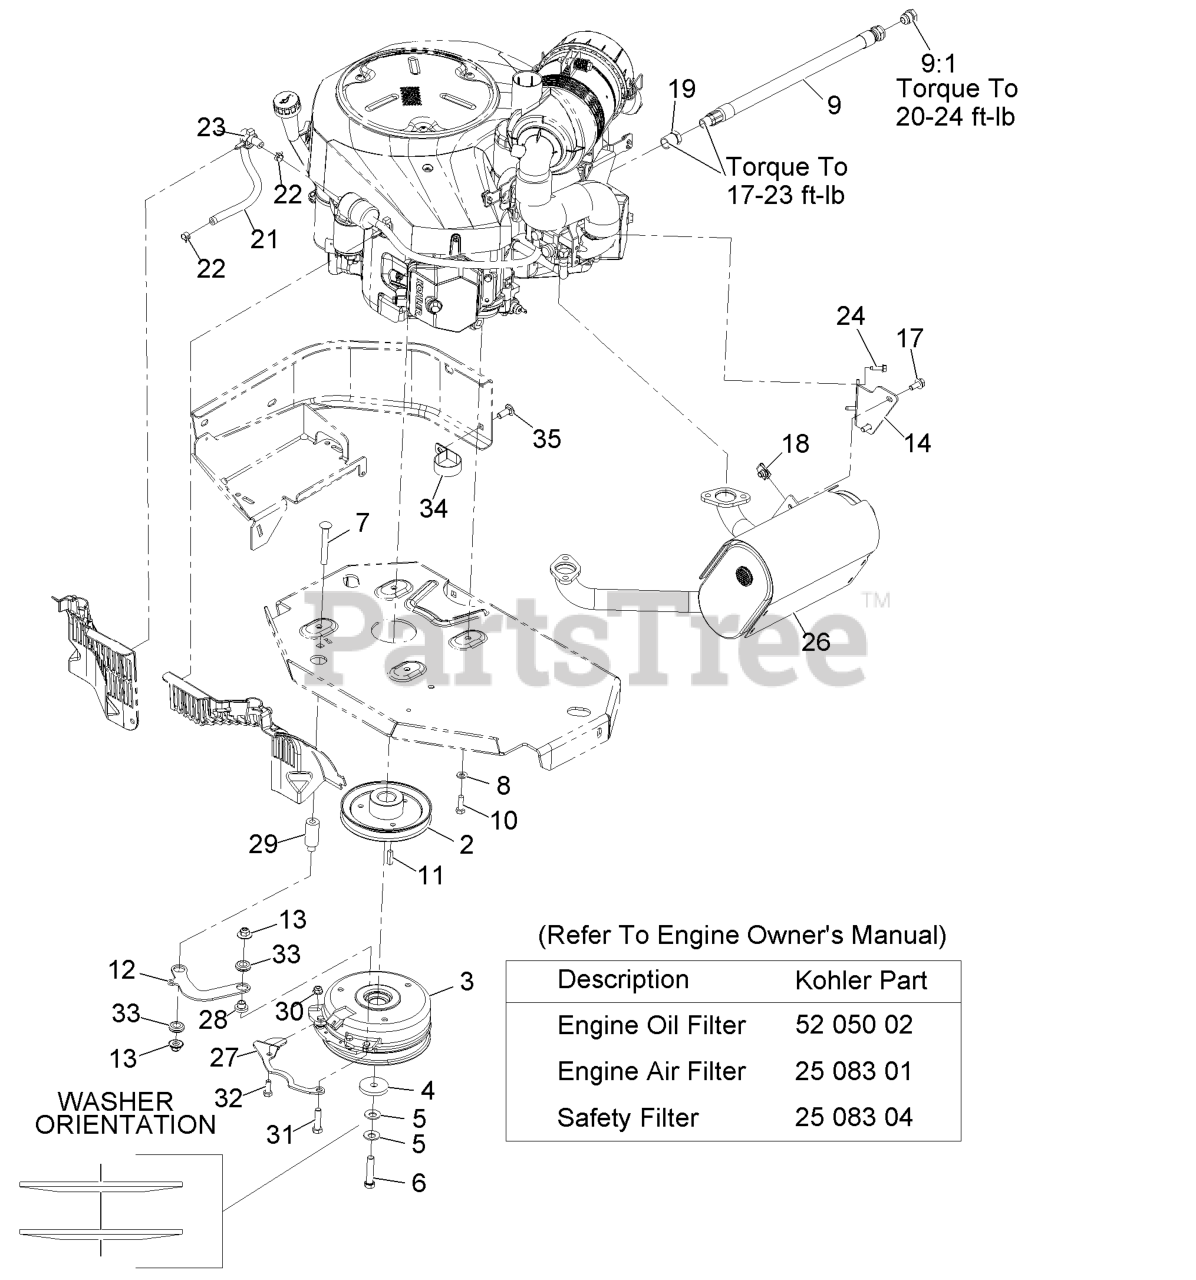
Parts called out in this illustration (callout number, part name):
2	SHEAVE
4	WASHER-CLUTCH
5	WASHER-SPRING
6	SCREW-HH W/LOCTITE
7	SCREW-CARR
8	WASHER-SPRING
10	SCREW-HH
12	LINK-ANCHOR, CLUTCH
13	Nut-Nyloc 3/8-16 Flg
17	SCREW-HHF
19	BUSHING
22	CLAMP-HOSE
23	CLAMP-HOSE
26	MUFFLER
27	BELT-GUIDE
30	NUT-HF, NI
31	SCREW-HH
32	SCREW-HH
33	GROMMET-RUBBER
34	CLAMP-R
35	SCREW-CARR
